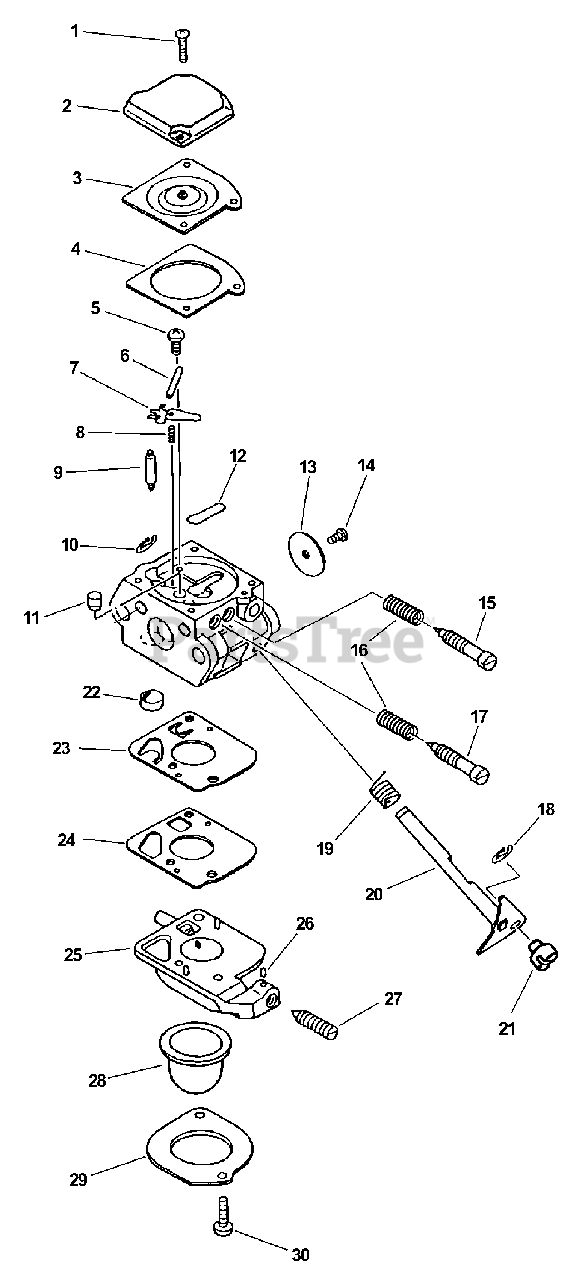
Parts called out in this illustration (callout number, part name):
2	COVER, METERING
3	DIAPHRAGM
4	GASKET, METERING
5	SCREW, METERING LEVER PIN
6	PIN, METERING LEVER
7	LEVER, METERING
8	SPRING, METERING LEVER
9	VALVE, INLET NEEDLE
10	RING, RETAINING
11	NOZZLE, CHECK VALVE
12	PLUG, WELCH
13	VALVE, THROTTLE
15	NEEDLE - HIGH SPEED
17	NEEDLE - LOW SPEED
18	RING, RETAINING
19	SPRING, RETURN
20	SHAFT, THROTTLE
22	STRAINER
23	DIAPHRAGM, PURGE
24	GASKET, PURGE
25	BASE, PURGE
26	PIECE, FRICTION
27	SCREW, IDLE ADJUST
28	BULB, PURGE
29	RETAINER, PURGE BULB
30	SCREW, RETAINER
31	DIAPHRAGM/GASKET KIT
32	REPAIR KIT
